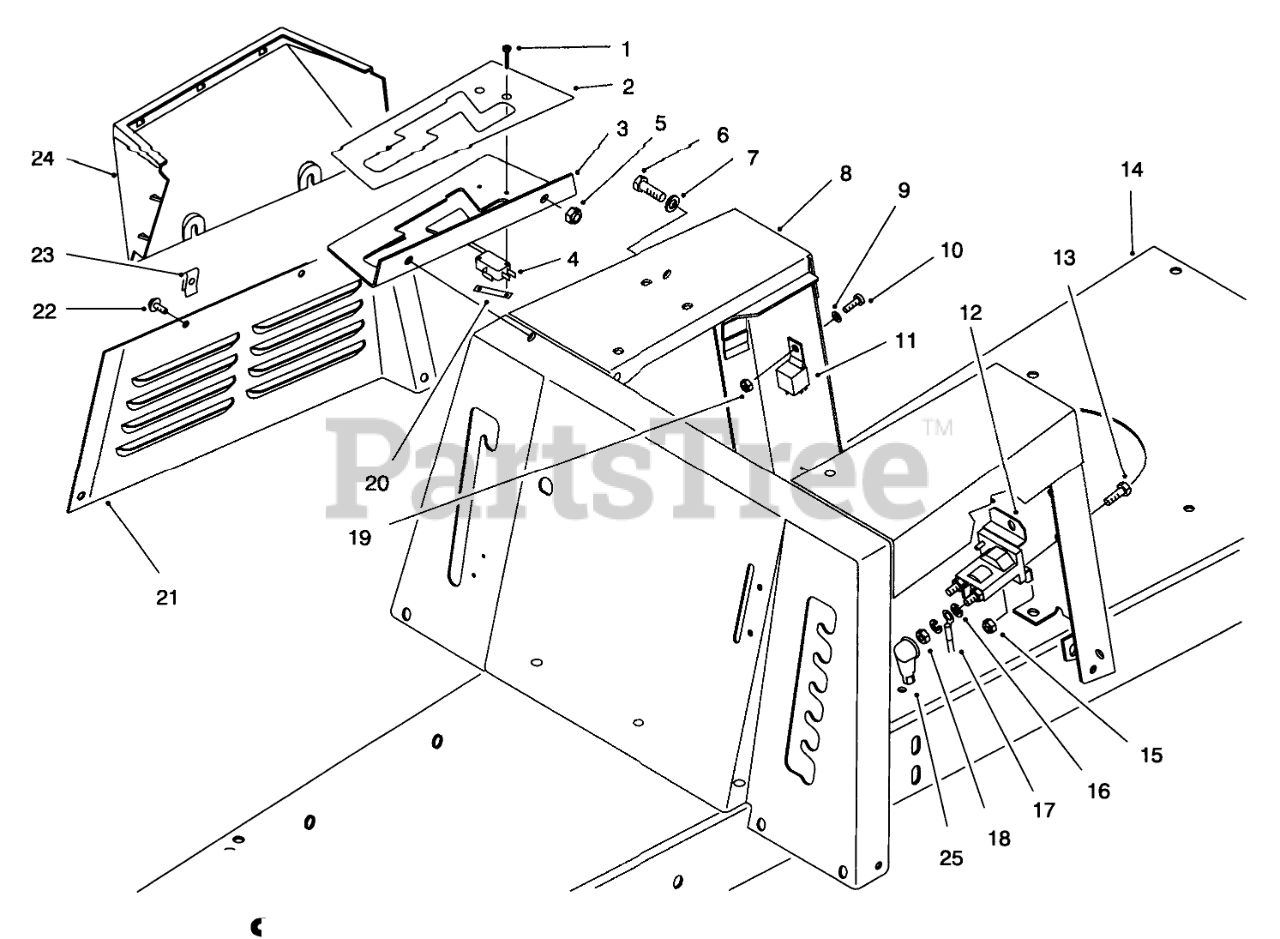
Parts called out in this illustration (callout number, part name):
1	SCREW-HH
2	DECAL - SHIFT PATTERN
3	Gate-Shift
4	SWITCH-MICRO
5	NUT-LOCK, NI
6	SCREW-HH
7	WASHER-PLAIN
8	Body W.A.-Seat Support
9	WASHER-FLAT
11	RELAY
12	SOLENOID
13	SCREW-HH
14	Frame
15	NUT-LOCK, NI
16	WASHER-LOCK
17	WIRE ASM
18	NUT-JAM
19	NUT-LOCK, NI
20	NUT-SPEED
21	Panel-Seat Base, R.H.
22	SCREW-HWH
23	NUT-CLIP,U
24	COVER-SHIFT GATE
25	BOOT-INSULATOR, TERMINAL
